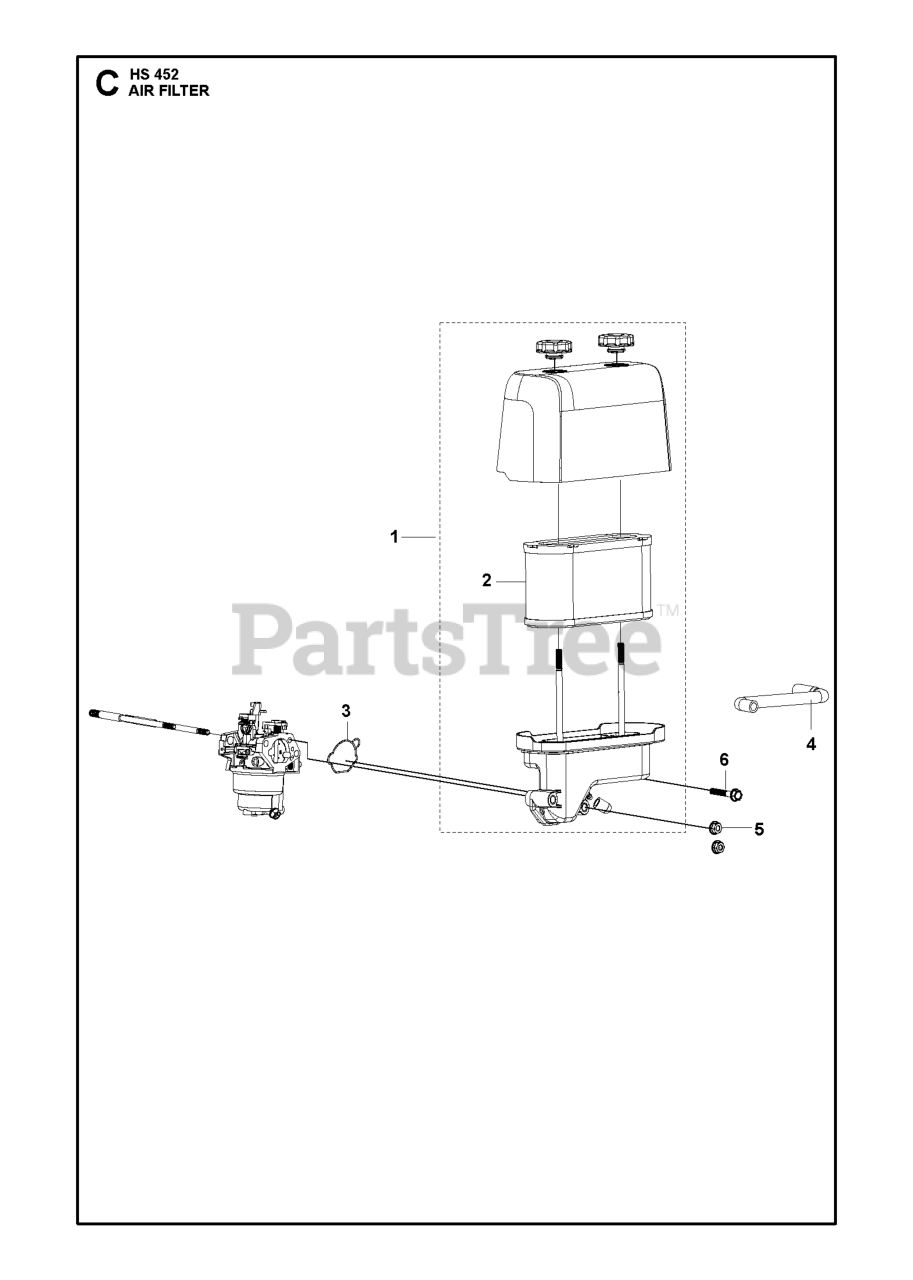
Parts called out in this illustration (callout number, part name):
1	AIR FILTER ASSY
2	SERVICE KIT KIT.AIR.FILTER ELE
3	GASKET CARBURETTOR GASKET
5	NUT GB/T 6177.1: M6
